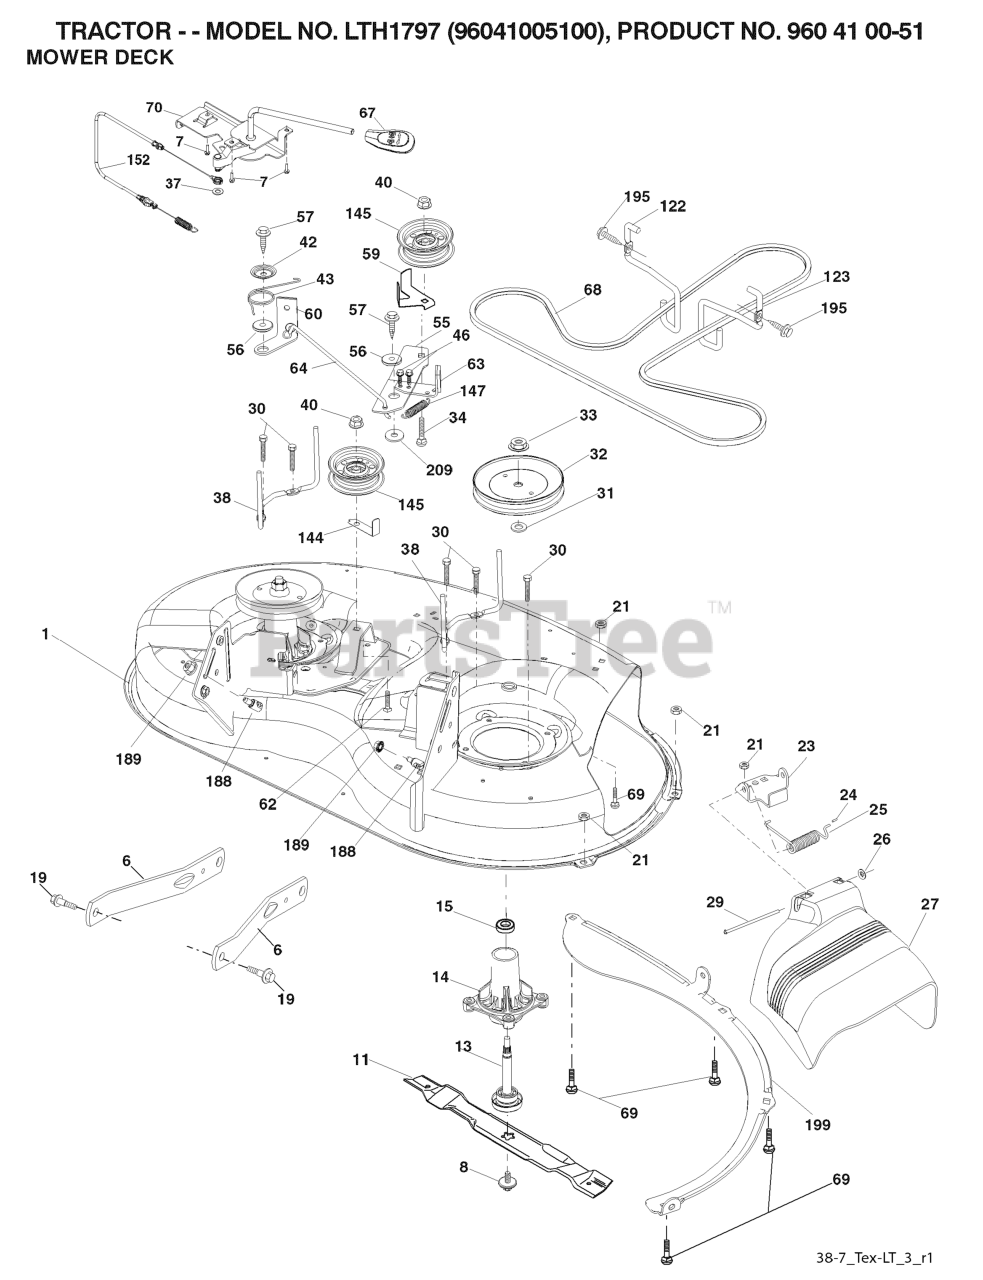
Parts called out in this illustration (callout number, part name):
1	HOUSING
6	ARM.SUSPENSION.MOWER.R
7	SCREW.#10 X 0.750.BOS
8	BOLT.WASHER.ASM.7/16-2
11	BLADE 38" PREMIUM
13	SHAFT.ASM.MDRL.N/GREASE.38
14	RP.HOUSING.MANDREL.4PT.
19	BOLT.SHOULDER
21	LOCKNUT
23	BRKT.DEFLECTOR.38"2005+
24	CAP-SLEEVE LT
25	SPRING.TORSION.DEFLECT
26	NUT PUSH M
27	SHIELD.DEFLECTOR.MWR.38-7/97CM
29	ROD.HINGE
30	SCREW, WASHER HEAD
31	WASHER.SPACER.MANDREL
32	PULLEY.MANDREL.5.0.PD.38"
33	NUT.FLANGE.LOCK.TOP
34	BOLT.3/8-16X1.50
37	WASHER
38	KEEPER BELT LH MANDREL
40	NUT LOCK FLG 3/8-16 UNC
42	SPRING.TORSION.BRAKE
43	SRPING.TORSION.RETAINE
46	SCREW.1/4-20X5/8
56	SPACER.RETAINER
57	SCREW 3/8-16X1
59	GUARD, BELT
60	ARM BRAKE MOWER RH 38"
62	BOLT.3/8-16X1.50
63	RP ARM.BRAKE.MOWER.38"LH.TEX
64	LINK BRAKE
67	HANDLE.CLUTCH.CABLE.LT
69	BOLT
70	CLUTCH.ASM.MANUAL.LT.PRED
122	KEEPER BELT ENGINE LH
123	KEEPER BELT RH
144	KEEPER BELT
145	PULLEY.IDLER.48"PRIMARY
147	SPRING RETURN
152	CLUTCH CABLE
188	STUD.FASTNER.W/ANTI-ROTATE
189	NUT LOCK HEX FLANGE 5/16-18
195	SCREW, 3/8-16X3/4
199	BAFFLE.VORTEX.FRONT.38"
209	WASHER 12/32X2X10GA
